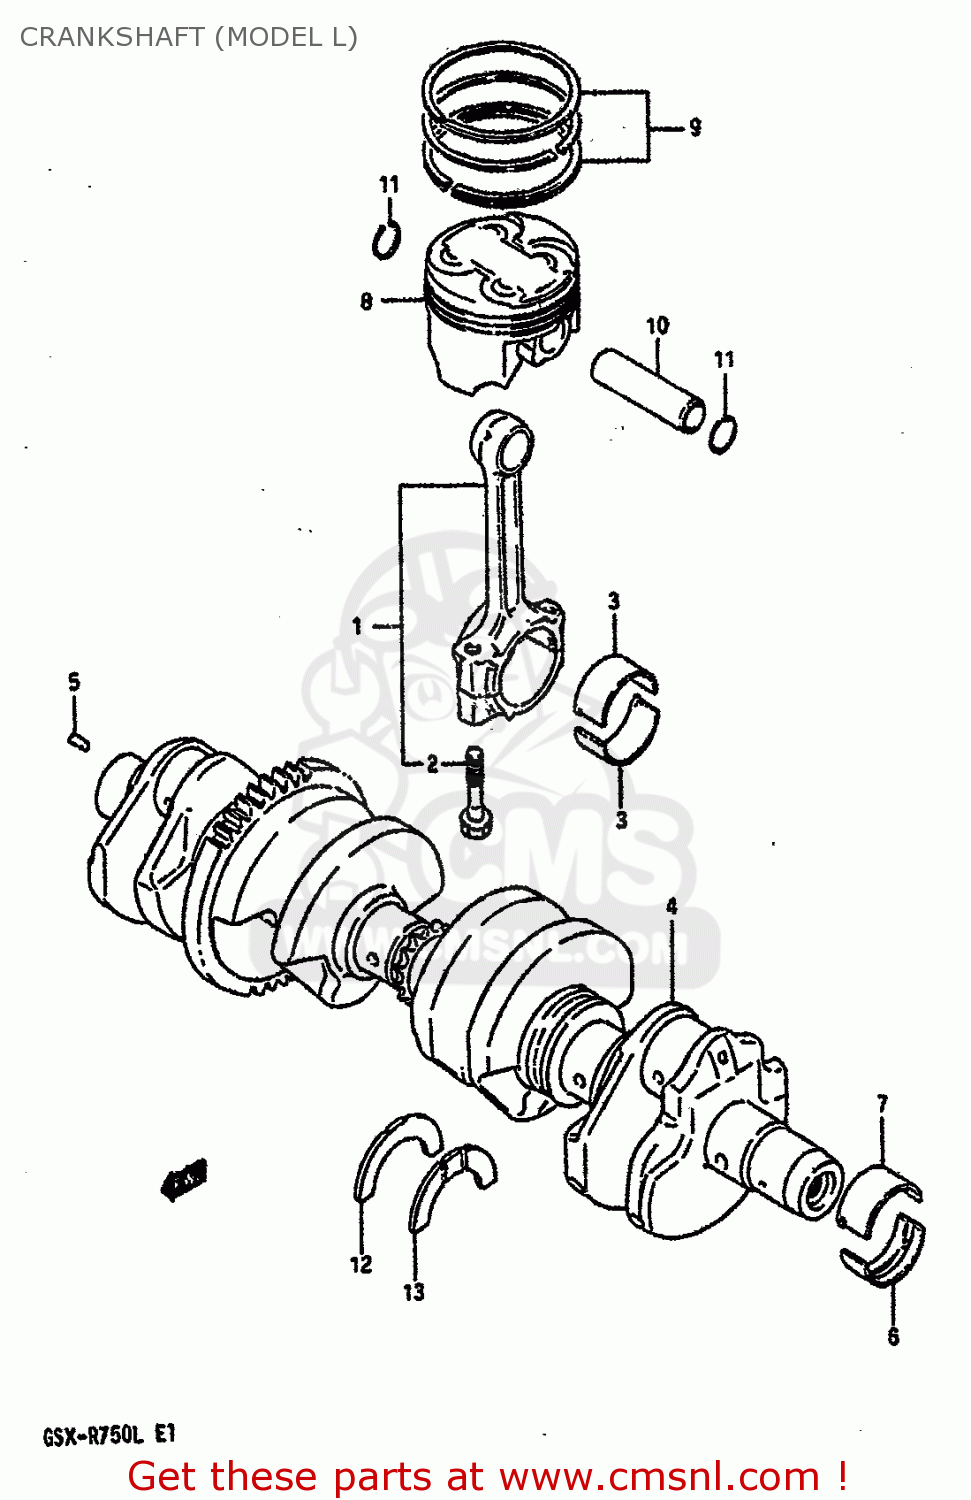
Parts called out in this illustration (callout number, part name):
1	ROD ASSEMBLY,CONNECTING
2	BOLT,CONNECTING ROD
3	BEARING,CRANK PIN
4	CRANKSHAFT
5	PIN
6	BEARING,CRANKSHAFT LWR
7	BEARING,CRANKSHAFT UPR
8	PISTON
9	RING SET,PISTON
10	PIN,PISTON
11	CIRCLIP
12	PLATE,CRANK THRUST
13	PLATE,CRANK THRUST
